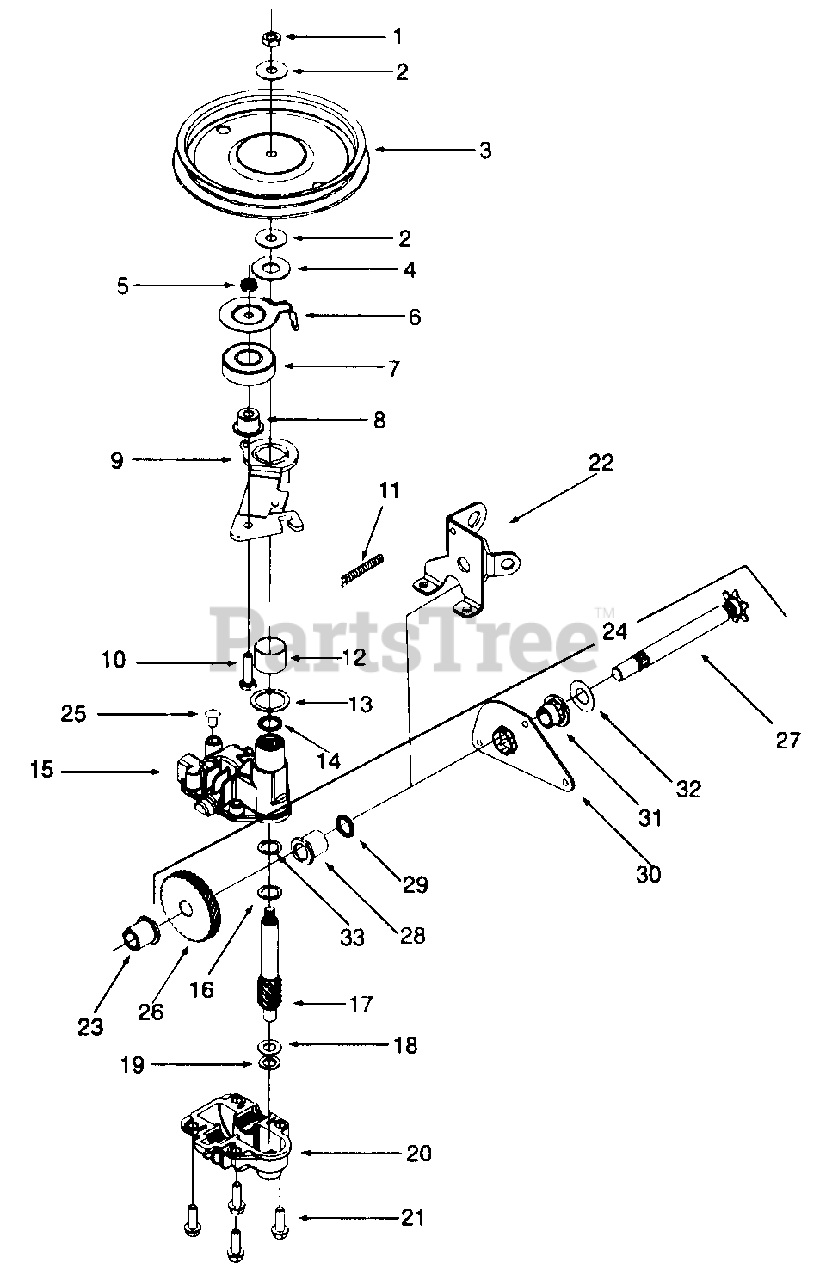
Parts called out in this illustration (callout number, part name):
1	Hx. Jam Nut 5/16-24
2	Bell Wash. .325 x .930 x .045
3	Pulley
4	Fl. Wash. .510 x 1.120 x .060
5	Hx. Jam Nut 1/4-28
6	Belt Keeper
7	Bearing
8	Flange Spacer
9	Idler Bracket Ass'y.
10	Hx. Cap Scr. 1/4-28 x 1.00 Gr. 5
11	Torsion Spring
12	Bearing Sleeve
13	Fl. Wash. .885 x 1.145 x.030
14	Oil Seal
15	Upper Housing Ass'y.
16	Fl. Wash. .504 x .700 x .030
17	Pinion Shaft 10 T.
18	Thr. Wash. 3/8 x .70 x .030
19	Thr. Wash. .388 x .625 x .062
20	Lower Housing Ass'y.
21	Hx. Scr. 1/2-20 x .75
24	Shaft Ass'y.
26	Gear 34 T.
27	Output Shaft 6 T.
28	Flange Bearing
29	Oil Seal
30	Pivot Bracket
31	Flange Bearing
32	Wash. Fl. .508 I.D. x 1.00 O.D. x .020
33	Thrust Bearing
